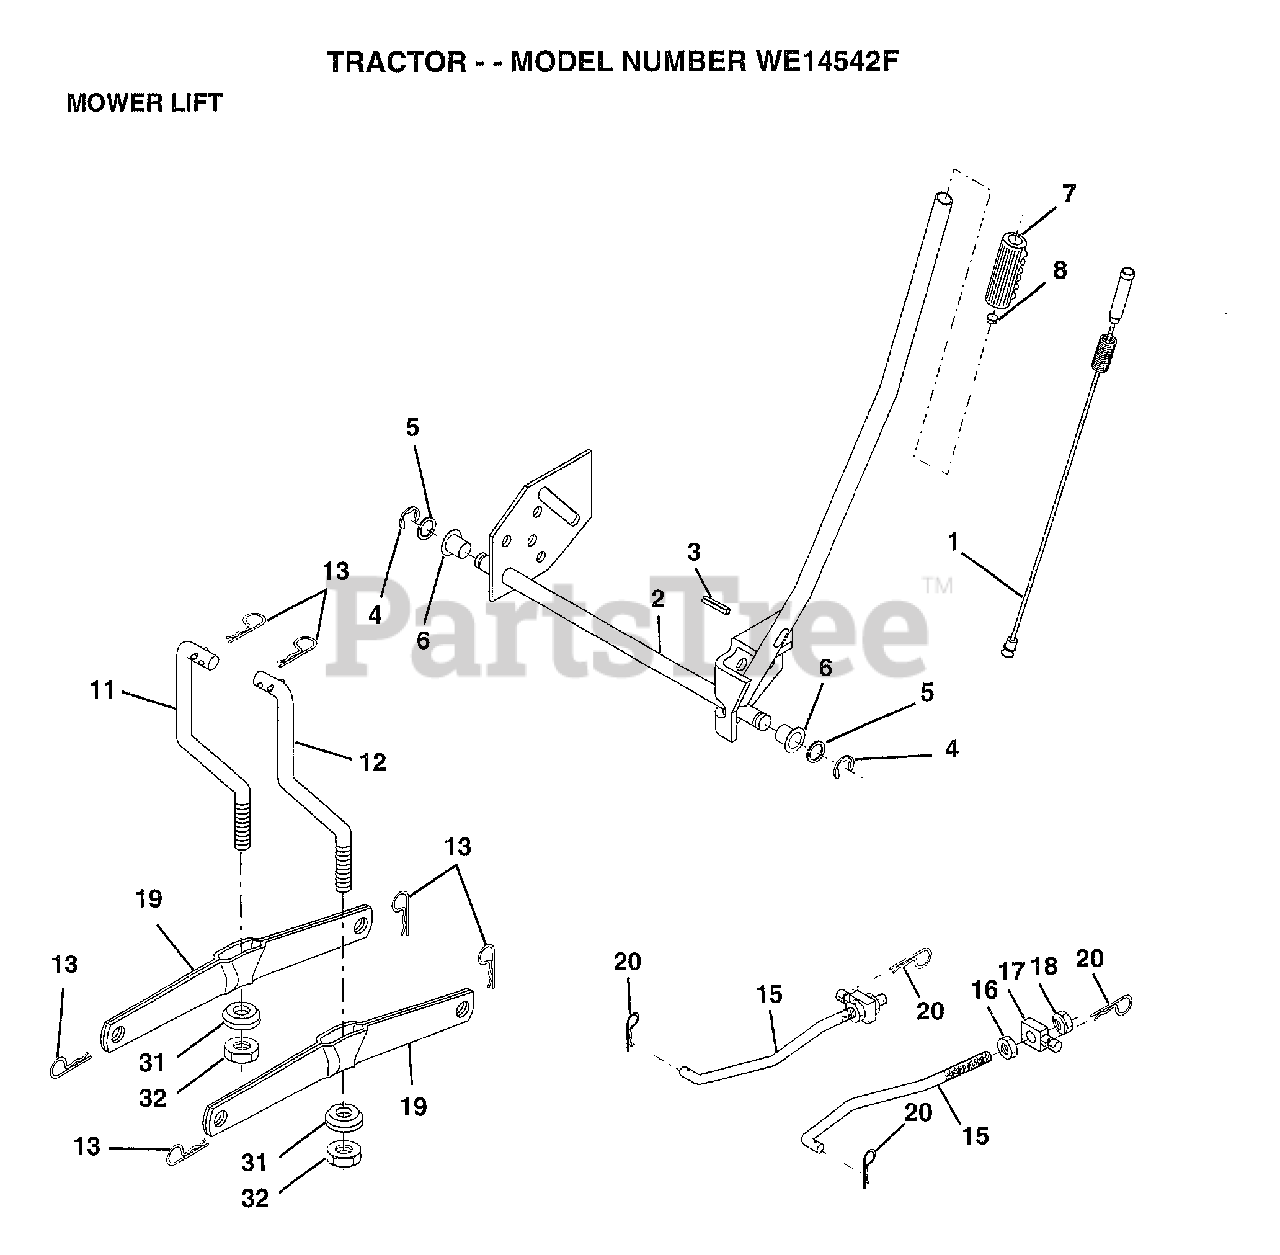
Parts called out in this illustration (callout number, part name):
1	WIRE ASM W.SPRING
2	"SHAFT ASM LIFT,RH"
3	PIN-GROOVE LT
5	WASHER
6	NYLON BEARING
7	GRIP
15	LINK.FRONT
16	NUT
17	TRUNION
18	NUT.LK.W/WSH.1/2.
19	ARM SUSP REAR
20	RETAINER.SPRING
31	BEARING PVT LH
32	NUT.CROWNLOCK.3/8
